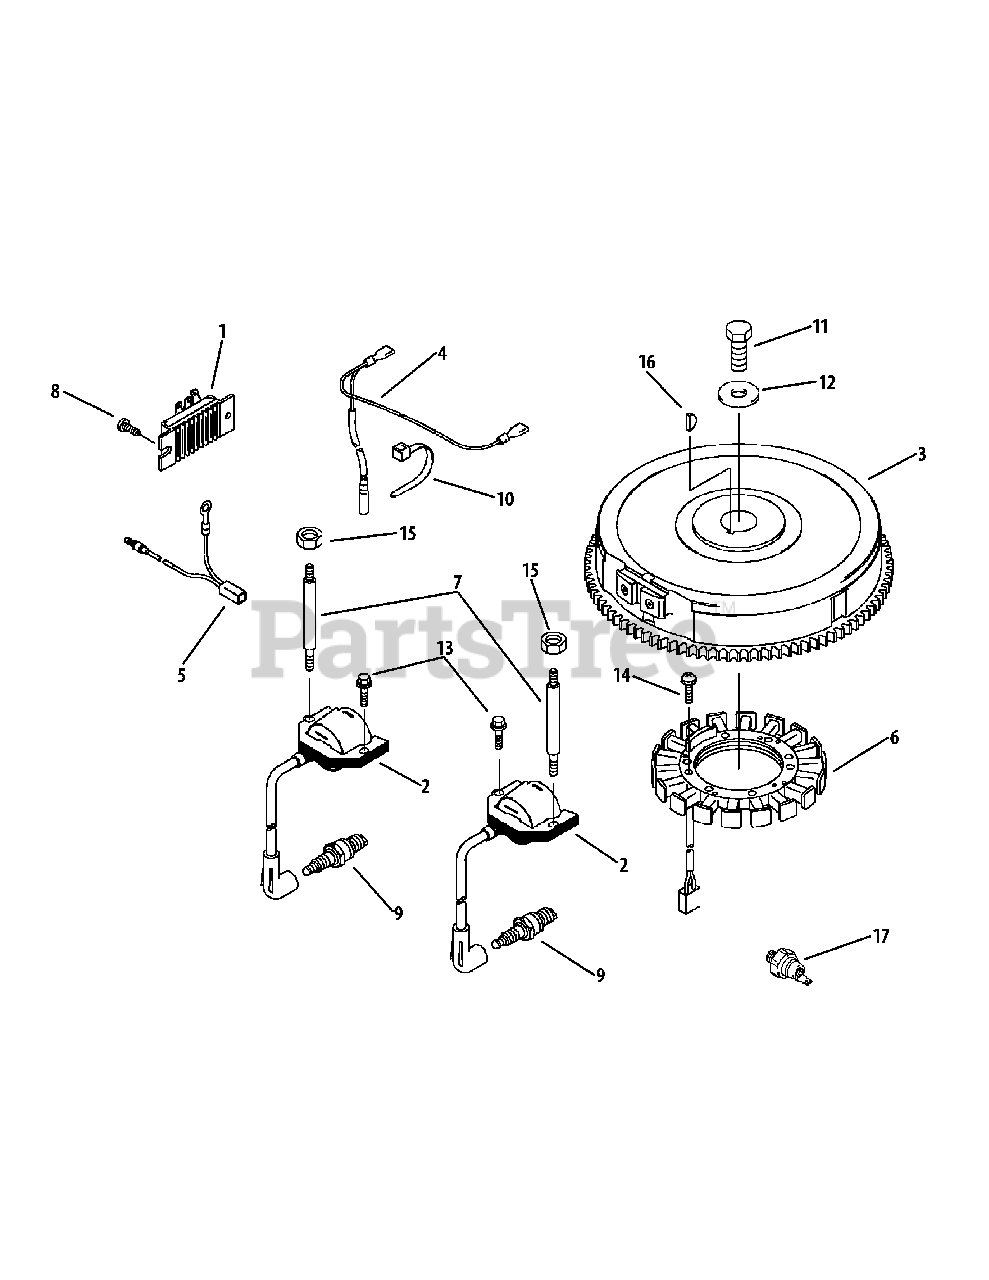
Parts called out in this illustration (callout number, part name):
1	Voltage Regulator
2	Ignition Coil
3	Flywheel
6	Charging Coil
7	Stud
9	Spark Plug (NGK)
11	Bolt, 12 x 30
13	Flange Bolt, 6 x 20
14	Screw, 5 x 20
15	Hex Nut
16	Woodruff Key
17	Oil Pressure Switch
